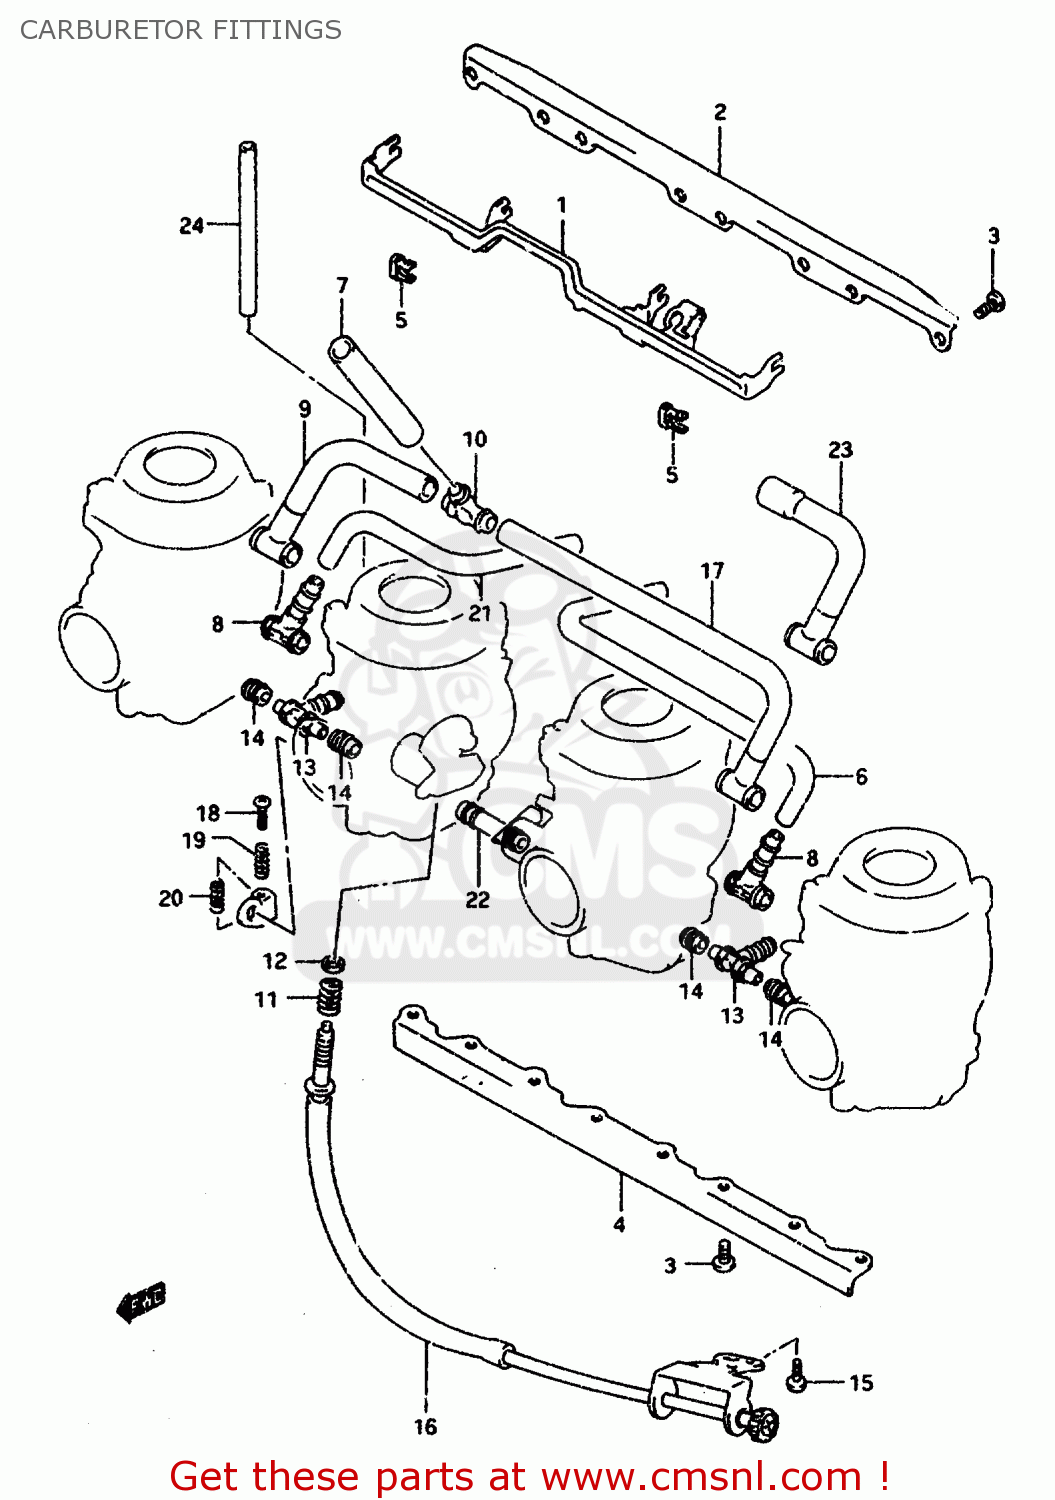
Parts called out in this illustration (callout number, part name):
1	LEVER,STARTER
2	PLATE
3	SCREW
4	PLATE
5	HOLDER
6	HOSE
7	HOSE (20X15X110)
8	HOSE
9	HOSE ASSEMBLY
10	NIPPLE
11	SPRING
12	WASHER
13	NIPPLE
14	SEAL
15	SCREW
16	ADJUSTER ASSY
17	HOSE ASSEMBLY
18	SCREW
19	SPRING
20	SPRING
21	HOSE
22	NIPPLE ASSY
23	NIPPLE ASSY
24	HOSE(5X9X600)
